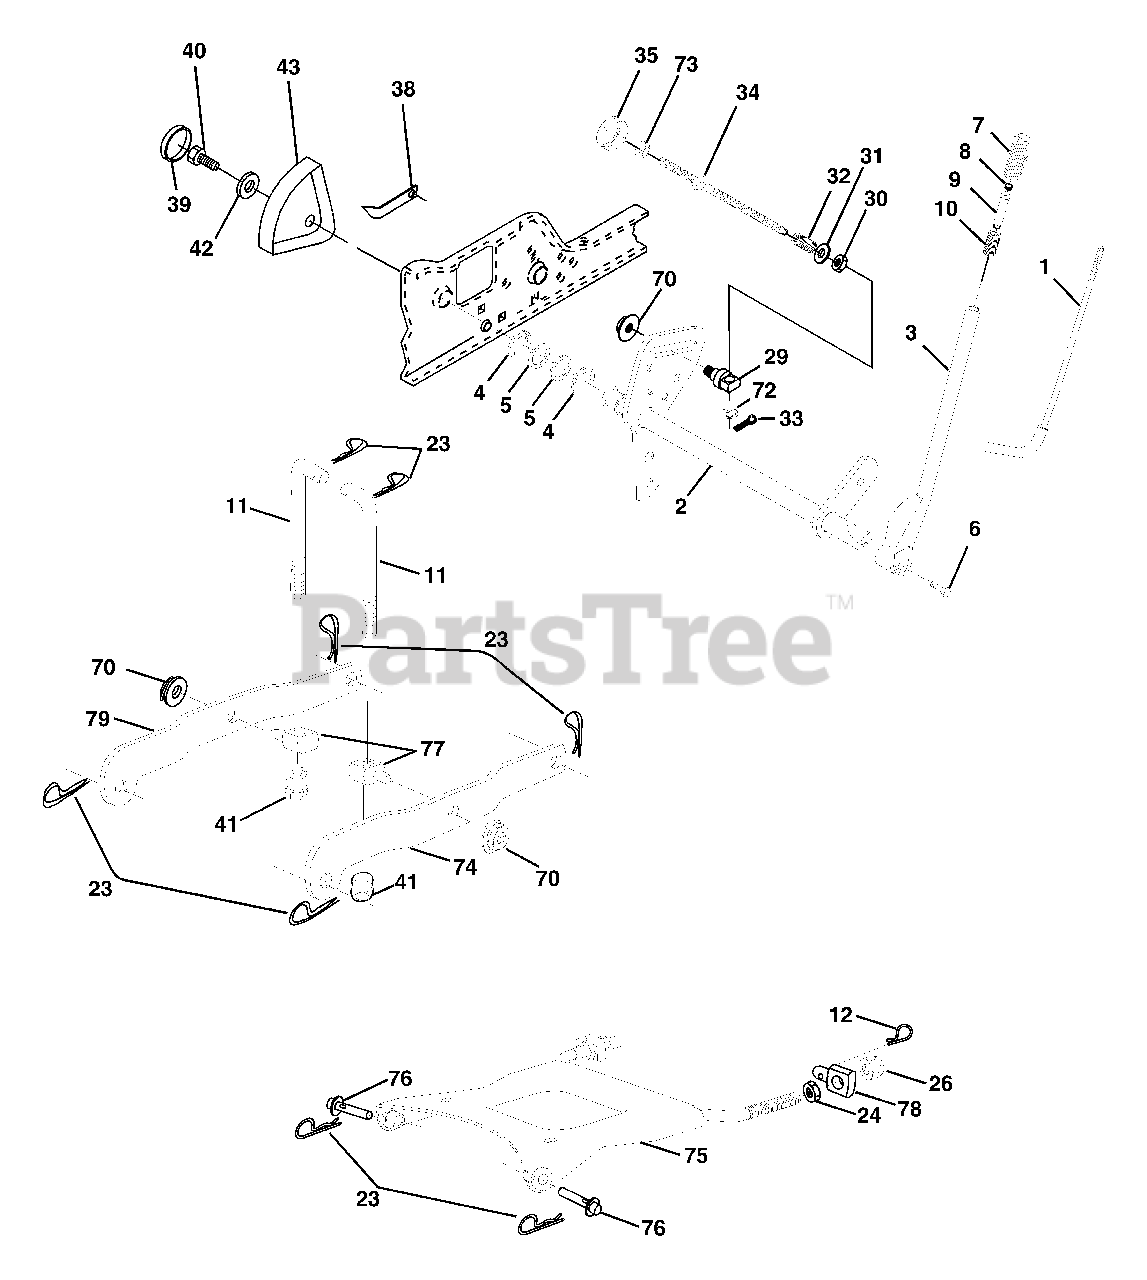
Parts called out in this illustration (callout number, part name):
1	Rod Asm., Lever
2	Shaft Asm., Lift Vgt
3	Lever Asm., Lift Rh
4	E-Ring Truarc #5133-87
5	Washer 29/32 x 1-1/4 x 16 Ga.
6	Bolt, Fin Hex 3/8-16 x 1-1/2
7	Grip, Handle
8	Button Plunger
9	Plunger, Lever Lift
11	Link Lift
12	Retainer, Spring
23	Retainer, Spring
24	Nut, Jam Hex 1/2-13 Unc
26	Nut Crownlock 1/2-13 Unc
29	Trunnion Infin Height
30	Nut, Special
31	Washer 13/32 x 5/8 x 16 Ga.
32	Spring, Compression Inf Hgt
33	Pin, Cotter 3/32 x 1/2
34	Rod, Adj Lift
35	Knob, Inf 3/8-16 Unc
38	Pointer Height Indicator
39	Plug, Hole Blk. 1.485/1.515 Dia.
40	Screw 5/16-18 x 1
41	Nut, Lift Link
42	Washer 11/32 x 1-1/2 x 10 Ga.
43	Scale, Indicator Height
70	Nut Hex Flange Lock
72	Nut Push Phos & Oil
73	Nut, Hex Jam 3/8-16 Unc
74	Arm, Suspension Rear RH
75	Plate, Asm, Susp, Front
76	Pin Flange
77	Trunnion Susp. Arm
78	Trunnion, Front, Susp
79	Arm, Suspension Rear LH
